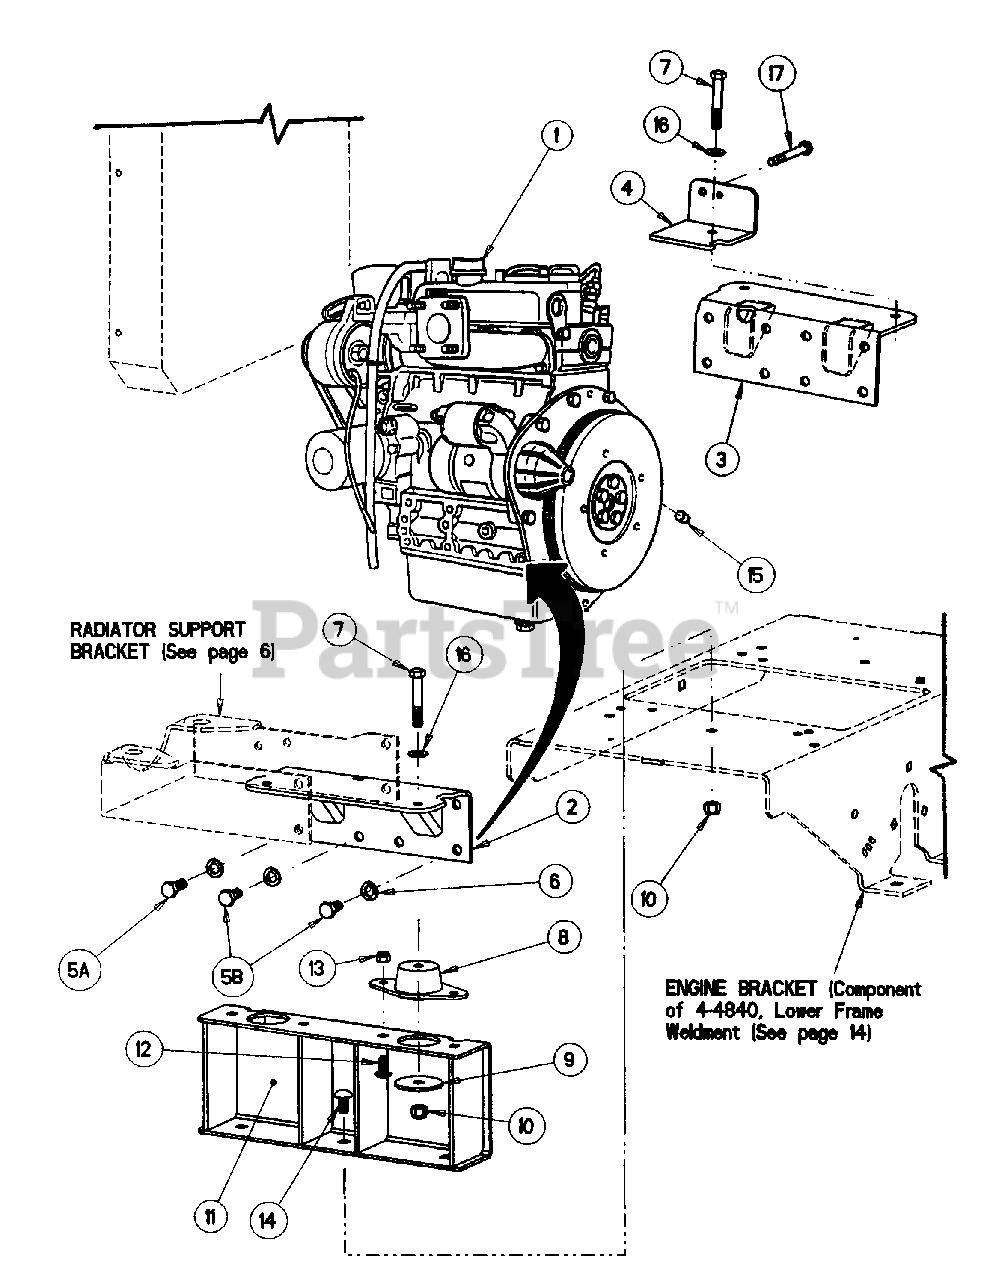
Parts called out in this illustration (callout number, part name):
2	MOUNT, Engine, Left Hand
3	MOUNT, Engine, Right Hand
4	BRACKET, Fuel Filter
5A	SCREW, M10-1.25 x 25mm
5B	SCREW, M10-1.25 x 20mm
6	WASHER, 7/16" Split Lock
7	BOLT, 3/8-16 X 2-1/2" GD5 CZ
8	MOUNT, Isolator
9	WASHER, Snubbing
10	NUT, 3/8-16 HEX NYLON LOCK
11	SUPPORT, Lower Channel
12	BOLT, 5/16-18 x 3/4" Short Neck Carriage, Grade 5
13	NUT, 5/16-18 HEX NYLON LOCK
14	BOLT, 3/8-16 x 1-1/4" Short Neck Carriage, Grade 5
15	PLUG, 1/4 Pipe
16	WASHER, 3/8" Flat
17	SCREW, 5/16-18 x 2-3/4" Hex Head Cap, Grade 5
